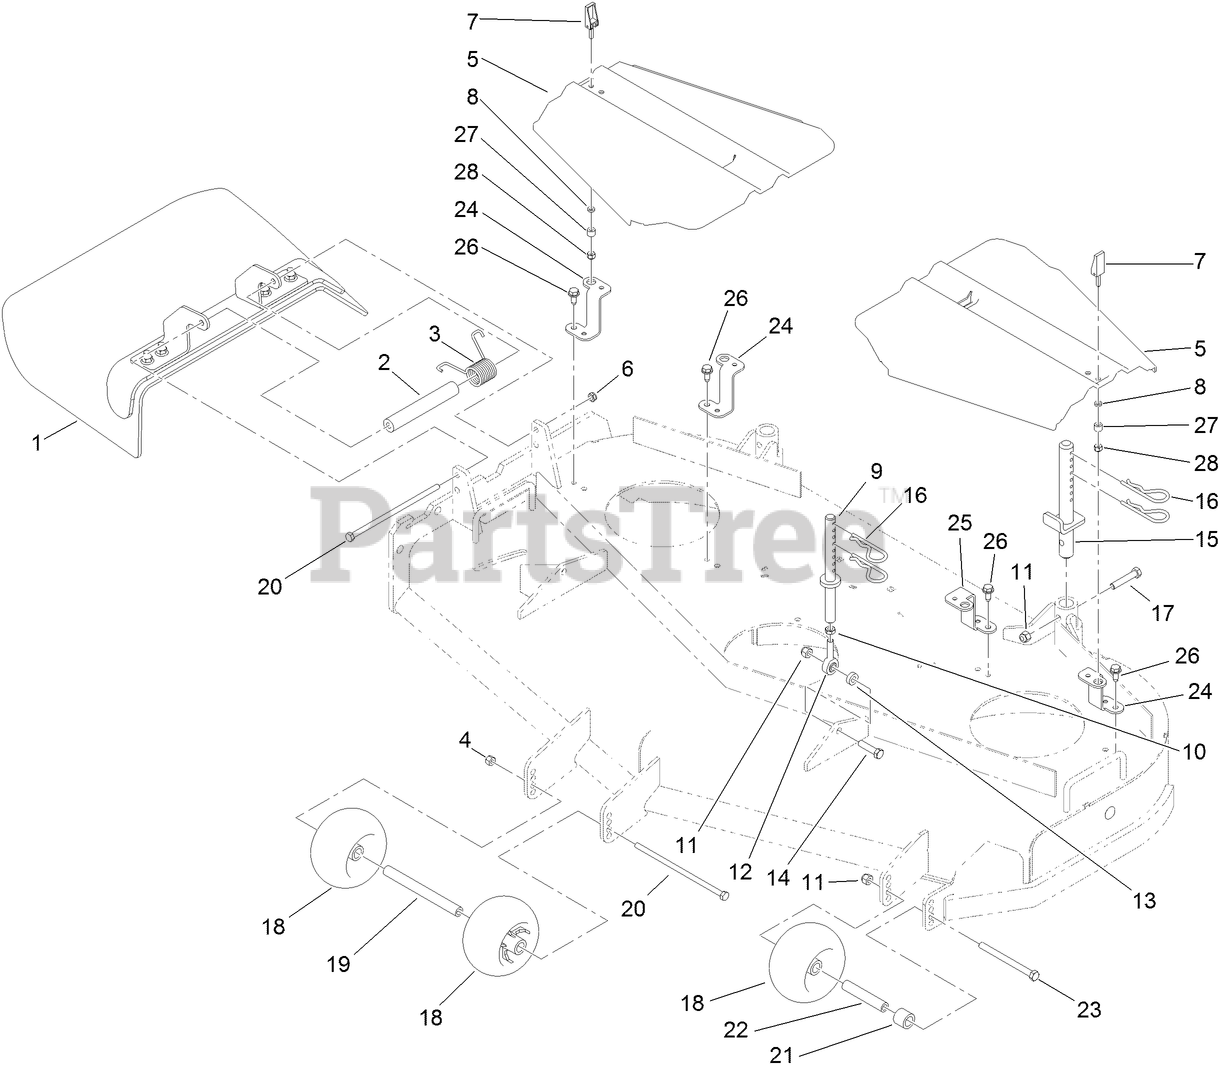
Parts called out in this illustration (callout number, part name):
1	DEFLECTOR ASM
2	SPACER
3	SPRING-TORSION
4	NUT-LOCK, NI
5	COVER-BELT
6	NUT-LOCK, NI
7	HANDLE-LATCH, SWELL
8	WASHER
9	FRONT PIN ASM
10	NUT-HJ
11	NUT-LOCK, NI
12	BALLJOINT
13	SPACER
14	SCREW-HH
15	REAR PIN ASM
16	PIN-HAIR
17	SCREW-HH
18	ROLLER-SCALP, ANTI
19	SPACER-WHEEL
20	SCREW-HH
21	TUBE-SPACER
22	TUBE-SPANNER
23	SCREW-HH
24	BRACKET-COVER
25	BRACKET-COVER
26	SCREW-HWHTF
27	BUSHING-LATCH, SWELL
28	NUT-LOCK, HH
